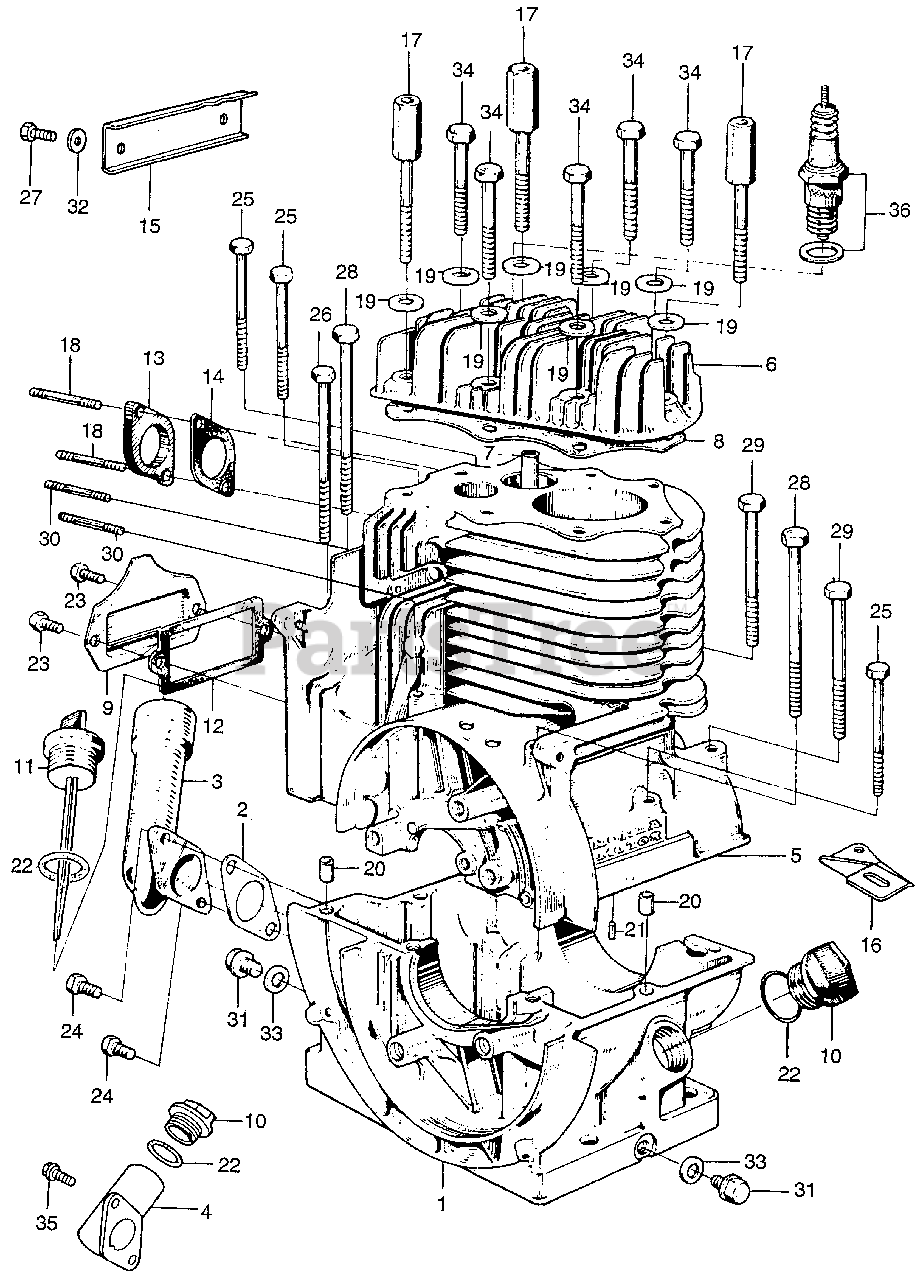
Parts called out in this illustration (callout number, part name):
2	GASKET, OIL PAN
3	PIPE, OIL (NOT AVAILABLE)
4	PIPE, OIL
6	CYLINDER HEAD
7	GUIDE, VALVE
8	GASKET, CYLINDER HEAD
9	COVER, TAPPET
10	CAP, OIL
11	CAP, OIL (NOT AVAILABLE)
12	GASKET, TAPPET COVER (NOT AVAILABLE)
13	INSULATOR, CARBURETOR (NOT AVAILABLE)
14	GASKET, CARBURETOR INSULATOR (NOT AVAILABLE)
15	BRACKET, SIDE COVER
16	STAY, ALTERNATOR (NOT AVAILABLE)
18	BOLT, STUD (8X39) (NOT AVAILABLE)
19	WASHER, HEAD (8MM)
20	PIN, KNOCK (8.5X11) (NOT AVAILABLE)
21	PIN, KNOCK (7X12) (NOT AVAILABLE)
22	O-RING (26X2.7)
23	BOLT, HEX. (6X12)
24	BOLT, HEX. (6X16)
25	BOLT, HEX. (6X63)
26	BOLT, HEX. (6X90)
27	BOLT, HEX. (8X16)
28	BOLT, HEX. (8X100)
29	BOLT, HEX. (8X80) (SOURCE: VINTAGE PARTS INC.)
30	BOLT 2, STUD (6X20)
31	BOLT, DRAIN PLUG (12MM)
32	WASHER, PLAIN (8MM)
33	WASHER, DRAIN PLUG (12MM)
34	BOLT, HEX. (8X45)
35	BOLT, FLANGE (6X32)
36	SPARK PLUG (B6HS) (NGK)
